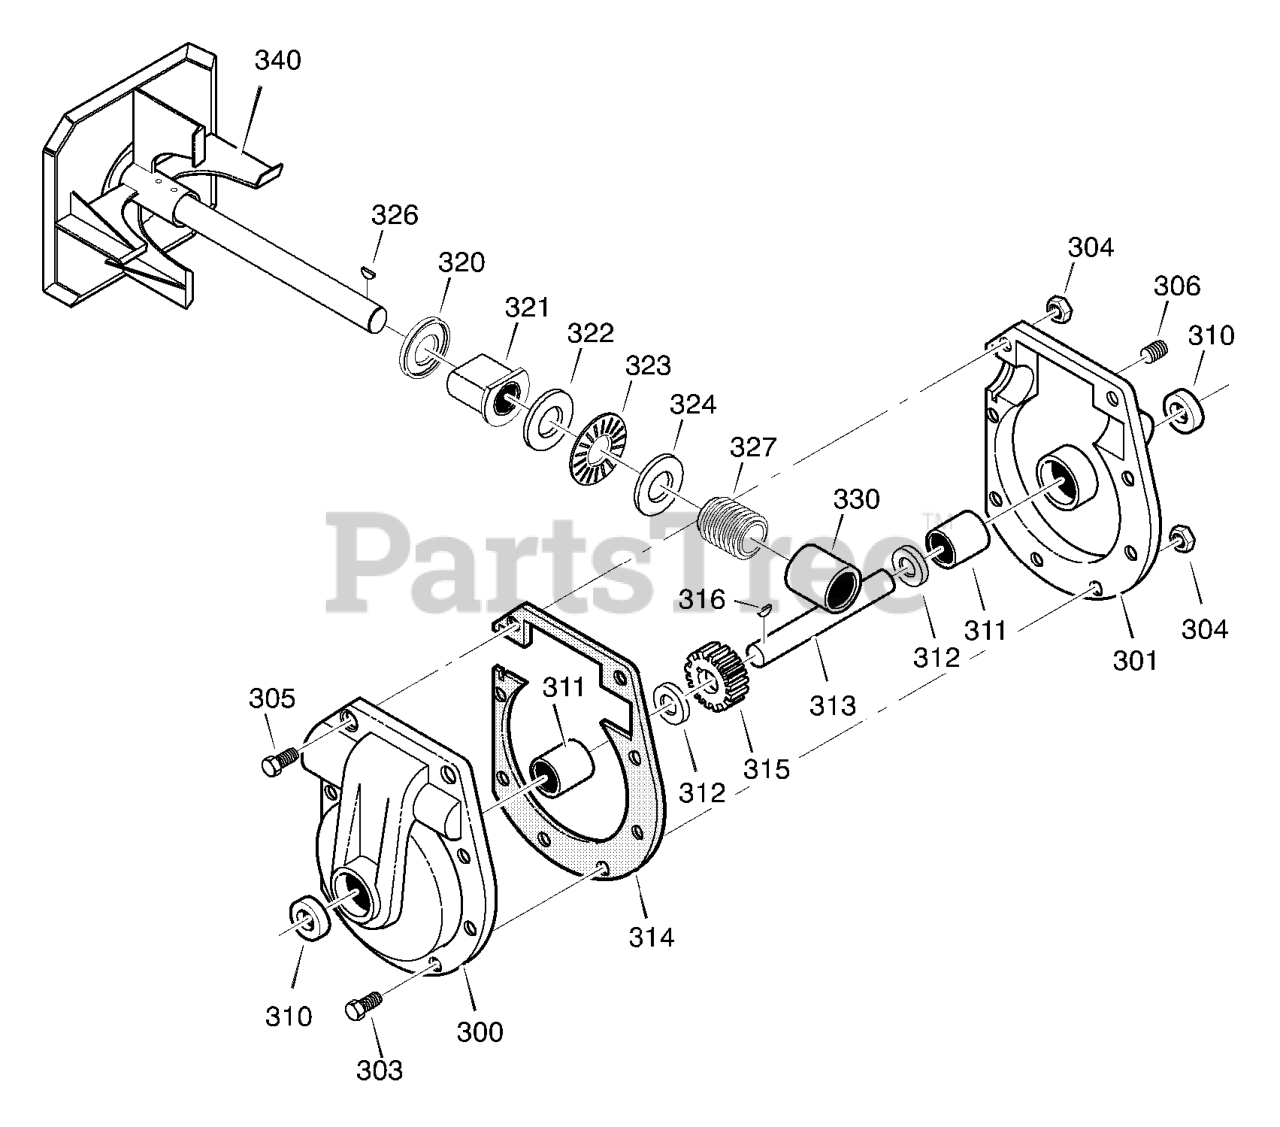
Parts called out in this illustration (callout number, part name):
300	CASE, GEAR, RH
301	CASE, GEAR, LH
303	SCREW,1/4-20X.75
304	NUT,1/4-20
305	NUT, 1/4-20 HEXKEPS
306	SCREW, 3/8-16 x 0.50
310	SEAL, OIL
311	BEARING, FL
312	WASHER, FLAT
313	SHAFT, AUGER OUTPUT
314	GASKET, GEAR BOX
315	WORM GEAR
316	KEY, WOODRUFF #61
320	BRNG, FL
321	SHAFT, AUGER INPUT
322	COLLAR, THRUST
323	PIN, SPRING
324	WASHER, FLAT
326	BRNG, FL
327	SEAL, OIL
330	BEARING
340	IMPELLER
